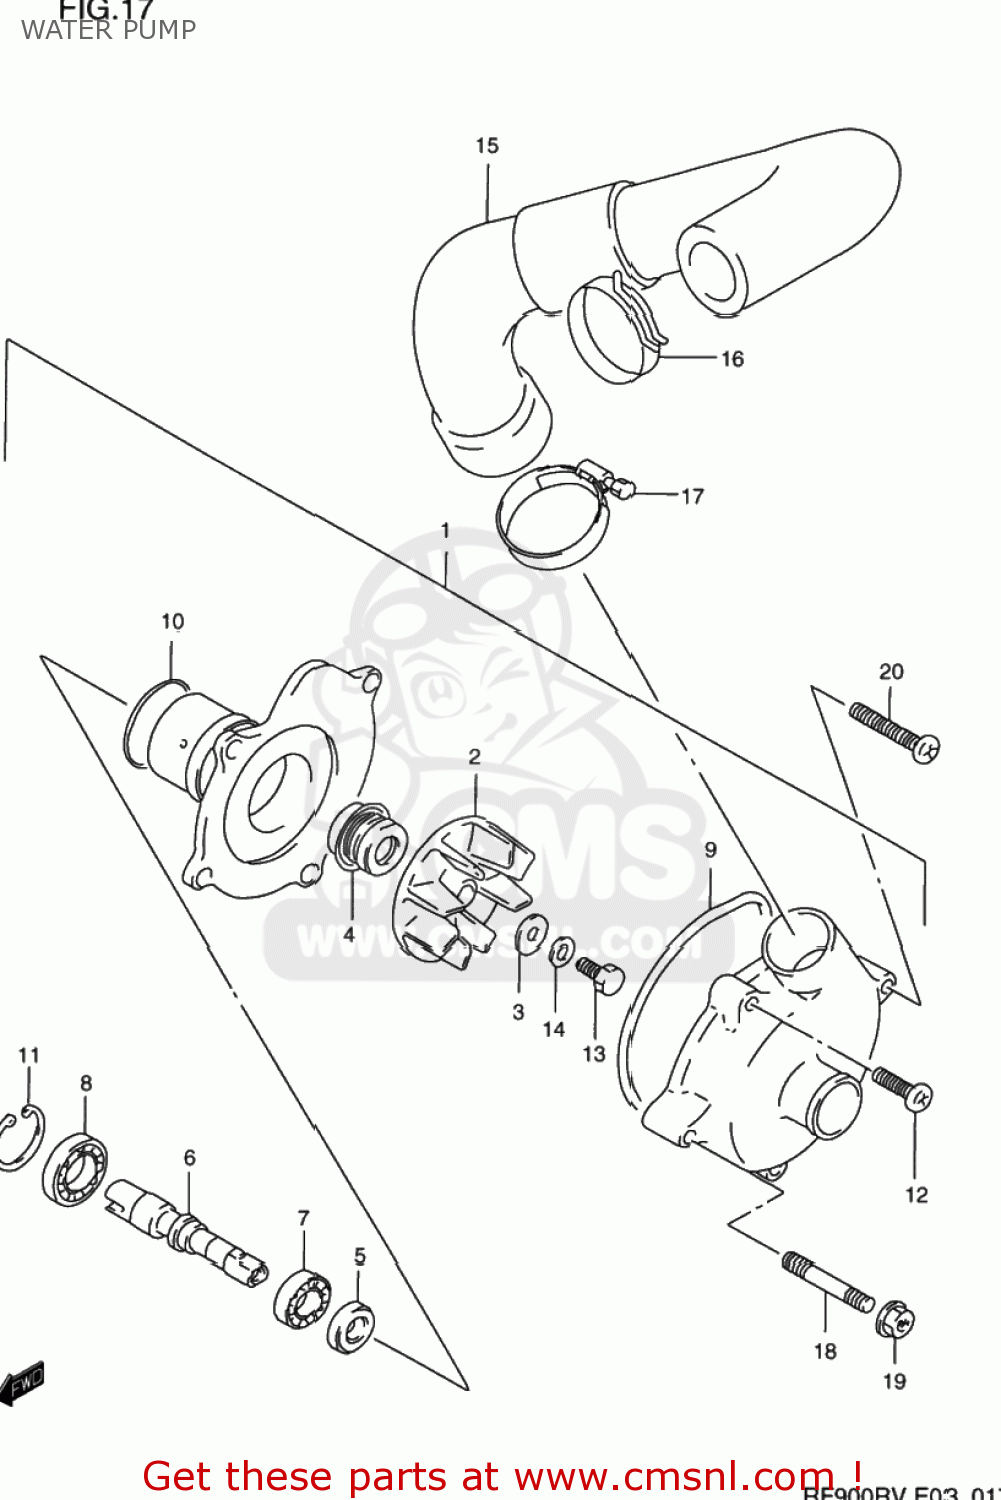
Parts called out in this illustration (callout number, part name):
1	PUMP ASSY,WATER
2	IMPELLER
3	GASKET(6X15X2.2) (NAS)
4	SEAL,MECHANICAL
5	OILSEAL
6	SHAFT
7	BEARING
8	BEARING(12X28X8)
9	O RING
10	O RING,WATER PUMP HOLDER
11	CIRCLIP
12	SCREW 6X16
13	BOLT(6X13)
14	WASHER
15	HOSE,WATER PUMP OUTLET
16	CLAMP
17	CLAMP
18	BOLT,STUD
19	NUT
20	SCREW
